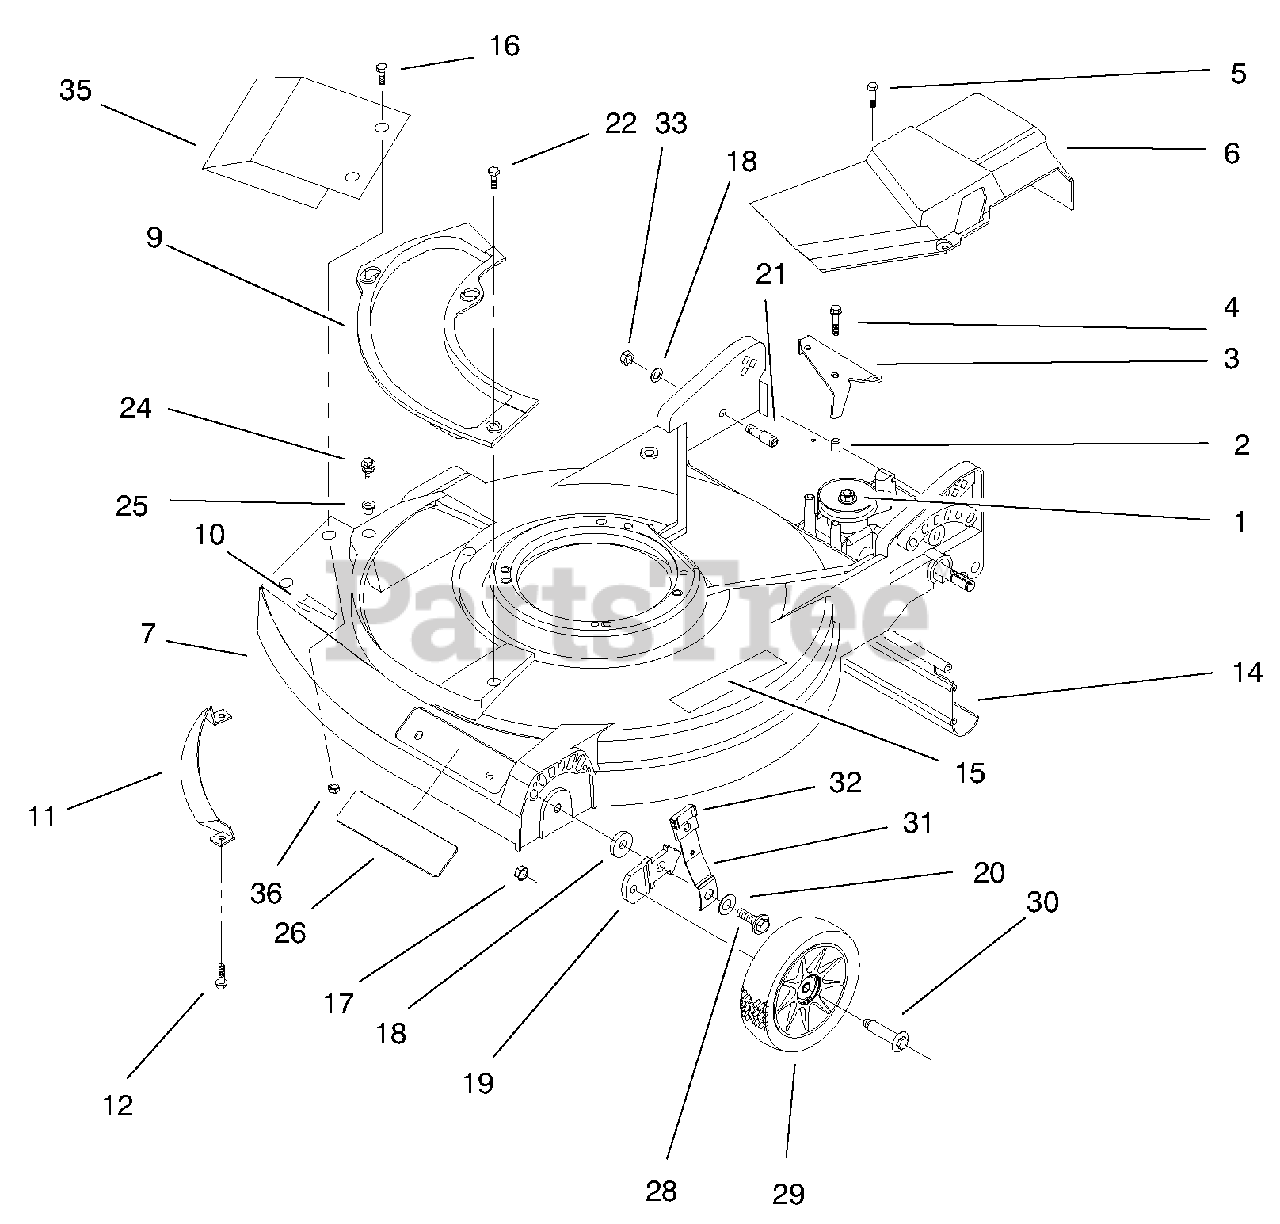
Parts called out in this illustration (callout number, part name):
1	ASM-Gear Case
2	Bushing-Spacer
3	Bracket-Actuator
4	Screw
5	Screw-Thread Forming
6	Cover-Drive
7	Housing-21" Sp
9	Plate-Cover
10	Decal-Deflector Danger
11	Toe Bar 21
12	Screw-HWH
14	Shield-Trailing
15	Decal-Danger
17	Nut-Lock
19	Bracket-Wheel Height Adj
20	Washer-Spring
21	Bolt-Shoulder
22	Screw-HH
24	Screw-Sems
25	Grommet-Plastic
26	Decal-Deck 550cs
28	Bolt-Shoulder
29	Wheel & Tire
30	Bolt-Wheel
31	ASM-Spring Arm
32	Knob-Height Adjust
33	Nut-Lock
35	Guard-Plate
36	Nut-Lock
